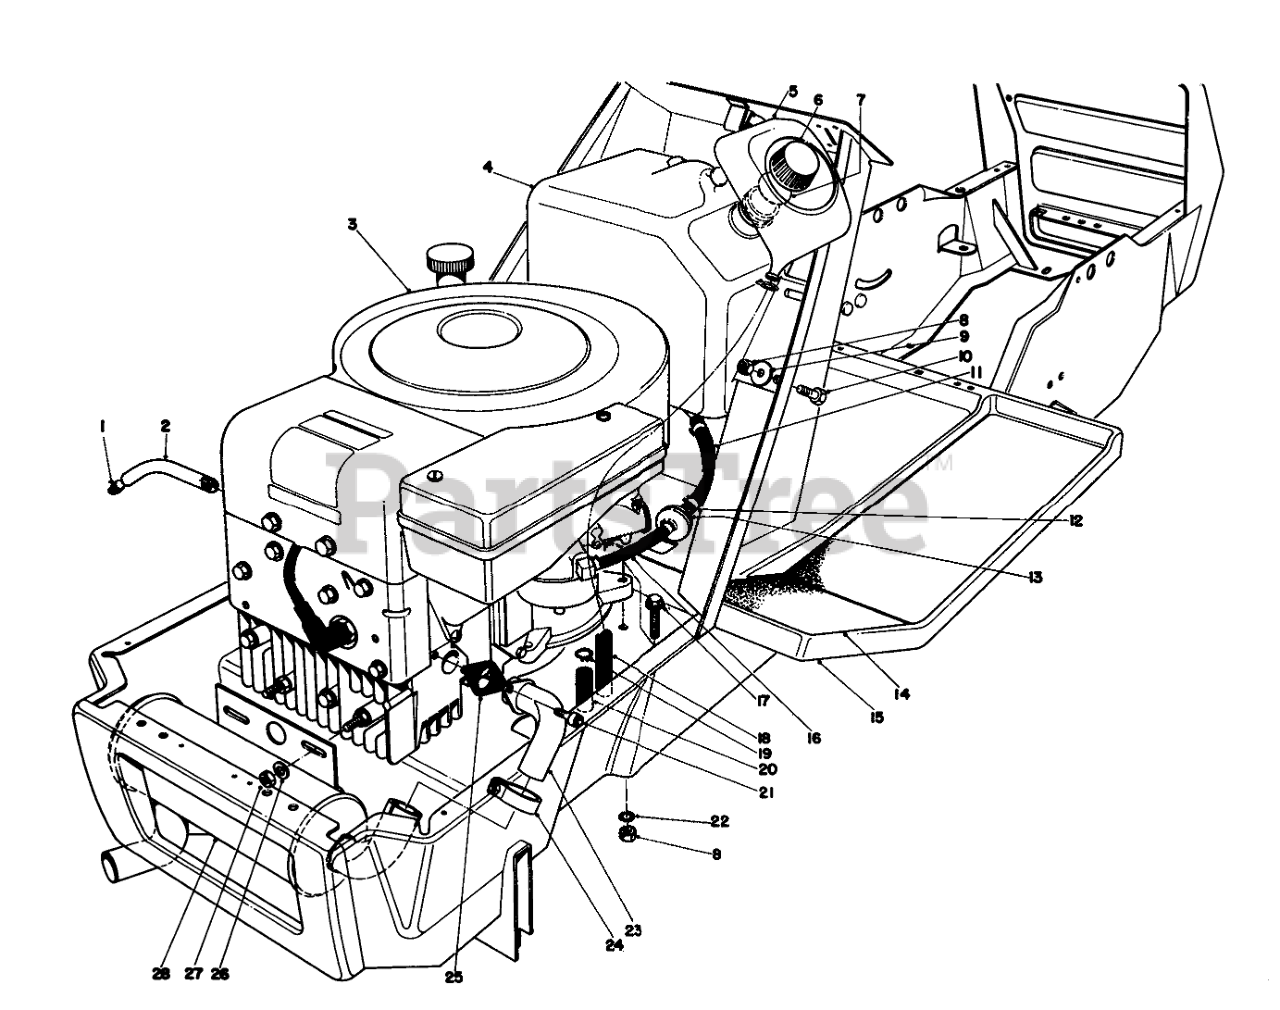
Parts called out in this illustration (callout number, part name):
1	PLUG-PIPE, SQH
2	OIL DRAIN TUBE
3	Engine
4	Gas Tank (Incl. Ref. #5)
5	Funnel-Overflow
6	Gas Cap (Incl. Ref. #7)
7	GAS CAP GASKET
8	NUT-LOCK, NI
9	WASHER
10	Screw
11	HOSE-FUEL
12	FUEL HOSE CLAMP
13	Fuel Filter
14	LH FOOT TREAD
15	Frame
16	Gas Hose
17	SCREW-HH
18	FUNNEL HOSE
19	HOSE CLAMP
20	CARB DRAIN HOSE
21	SCREW-HSH
22	WASHER-LOCK, INTERNAL
23	Exhaust Pipe
24	Clamp-Exhaust Pipe
25	Exhaust Gasket
26	WASHER-PLAIN
27	NUT-LOCK, CONE
28	MUFFLER
